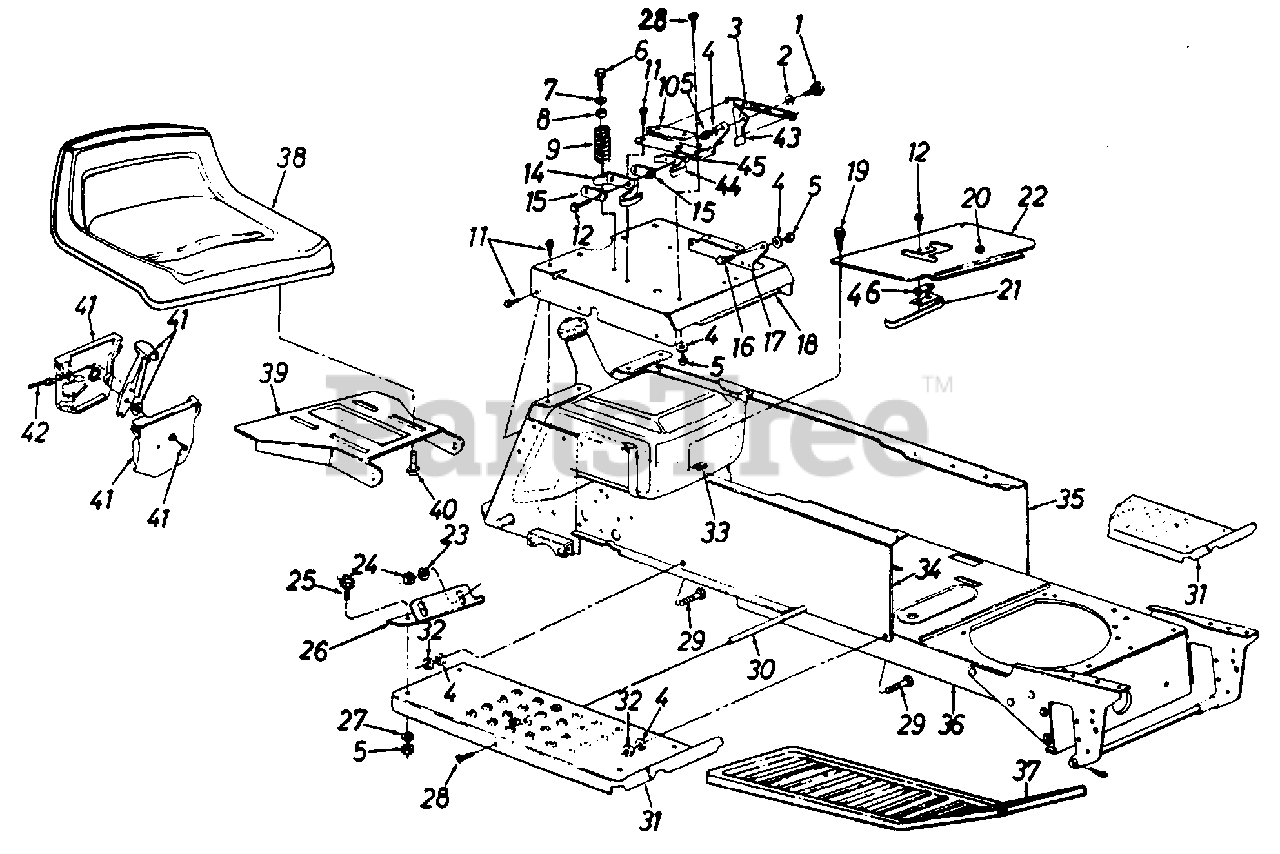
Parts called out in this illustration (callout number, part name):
1	Shld. Bolt .437" Dia. x .162n
2	Spr. Wash. .445" I.D.
3	Ext. Spring 5.31" Lg.
4	L-Wash. 5/16" I.D.
5	Hex Nut 5/16-18 Thd.
6	Hex Wash. Hd. Tap Scr. 5/16-18 x .7" Lg.
7	Fl-Wash..344" I.D.
8	Bushing
9	Compression Spring
12	Hex Wash. Hd. AB-Tap Scr. #8 x 5" Lg.
14	Spring Switch
15	Insulator Plate
16	Shld. Bolt .437" Dia. x .162"
19	Truss Mach. B-Tap Scr. #10 x .5" Lg.
20	Snap Bushing
21	Reverse Safety Switch (Model 840 thru 849 only.)
22	Shift Cover
23	L-Wash. 1/4" I.D.
24	Hex Nut 1/4-20
25	Hex Bolt 5/16-18 x 75n Lg.
28	Truss Mach. Scr. 5/16-18 x . 75" Lg .
29	Rib Neck Bolt 5/16-24 x .75" Lg.
30	Running Board Rod
33	Speed Nut #10Z
34	R.H. Side Frame
37	Rubber Foot Pad
38	Seat Ass'y.
39	Seat Pivot Bracket
40	Hex Tap Scr. 3/8-16 x .75" Lg.
41	Throttle Control Box Ass'y.
42	Throttle Control Wire 35" Lg.
43	Seat Lift Bracket
44	Seat Spring Switch
45	Insulator Boss Plate
46	Insulator Nut Plate (Model 840 thru 849 only.)
